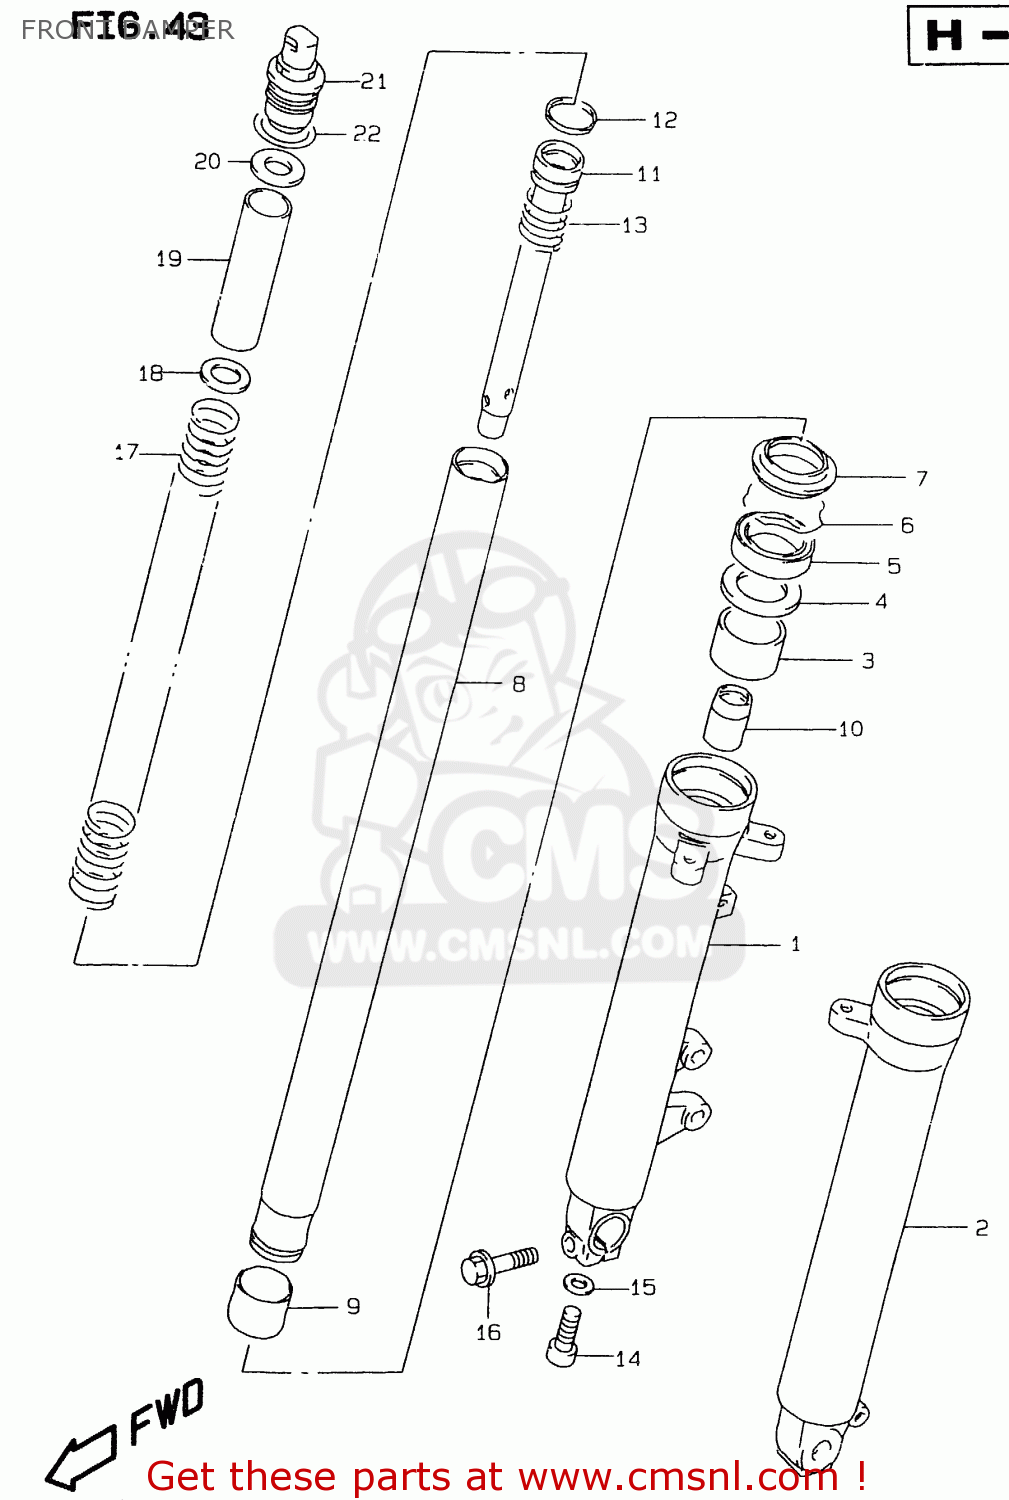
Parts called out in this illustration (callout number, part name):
1	TUBE,OUTER,R
2	TUBE,OUTER,L
3	METAL,SLIDE
4	WASHER
5	SEAL,OIL
6	RING,STOPPER
7	SEAL,DUST
8	TUBE,INNER
9	PISTON
10	PIECE,OIL LOCK
11	CYLINDER
12	RING,PISTON
13	SPRING,REBOUND
14	BOLT,FORK CYLINDER(10X25)
15	GASKET (NAS)
16	BOLT
17	SPRING,MAIN
18	WASHER
19	SPACER,FR FORK SPRING
20	WASHER,UPR
21	BOLT,FORK
22	O RING
